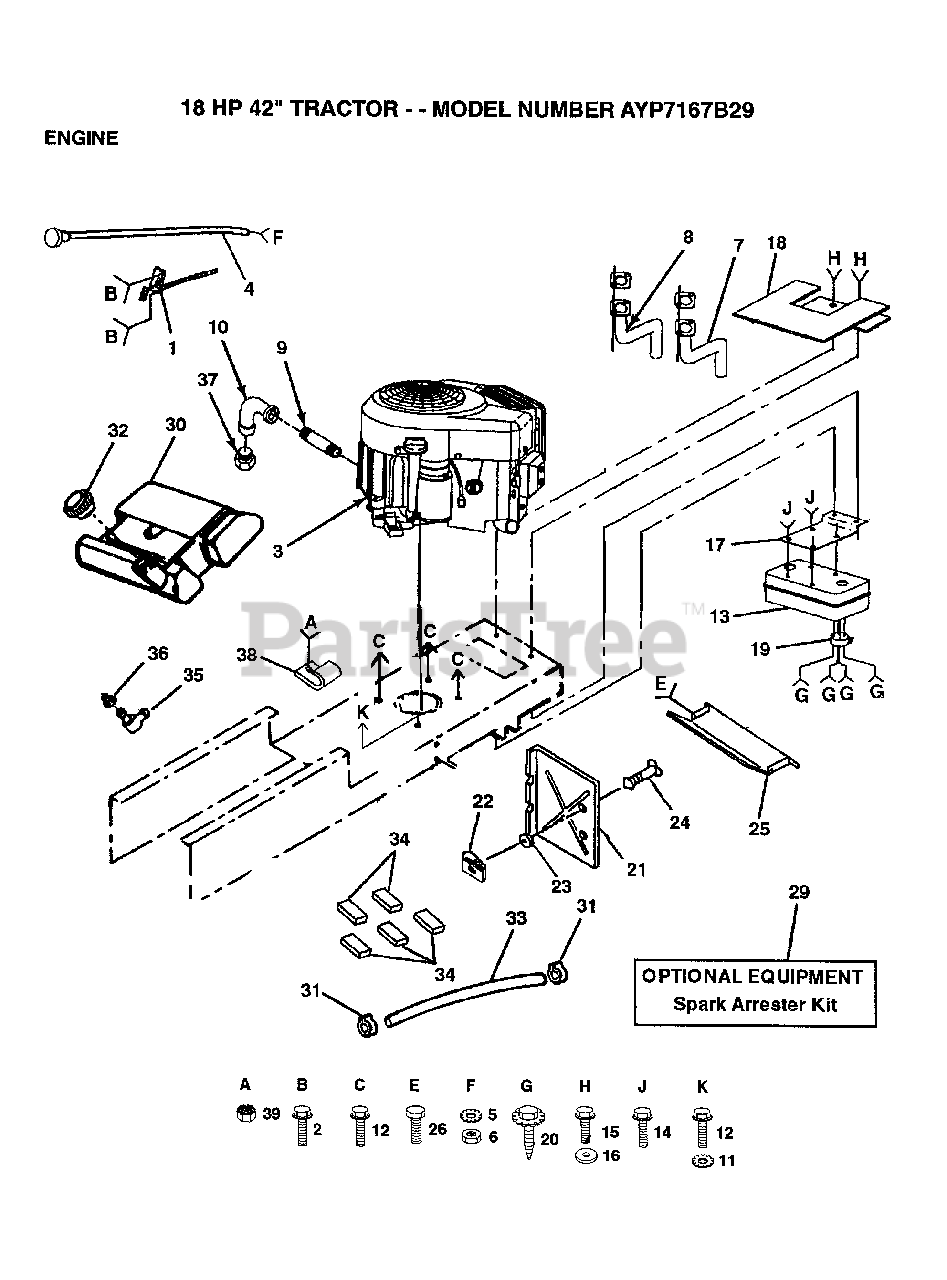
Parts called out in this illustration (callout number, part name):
2	SCREW LT
4	CHOKE CONTROL
5	LOCKWASHER
7	TUBE ASSY EXH RH
8	TUBE ASSY EXH LH
9	PIPE NIPPLE LT
10	ELBOW
11	LOCKWASHER
12	SCREW LT
14	SCREW ST
15	SCREW
16	WASHER
17	BRACKET MUFFLER
19	DEFLECTOR.222573
21	HEAT SHIELD
22	RECEPTACLE LT
23	RETAINER LT
24	STUD.1/4.TURN
25	HEAT SHIELD
26	SCREW
31	HOSE CLAMP
33	FUEL LINE T
34	PAD-SPACER LT
35	BUSHING OUTLET T
36	FUEL TANK STEM GT
38	CLIP T
39	NUT
